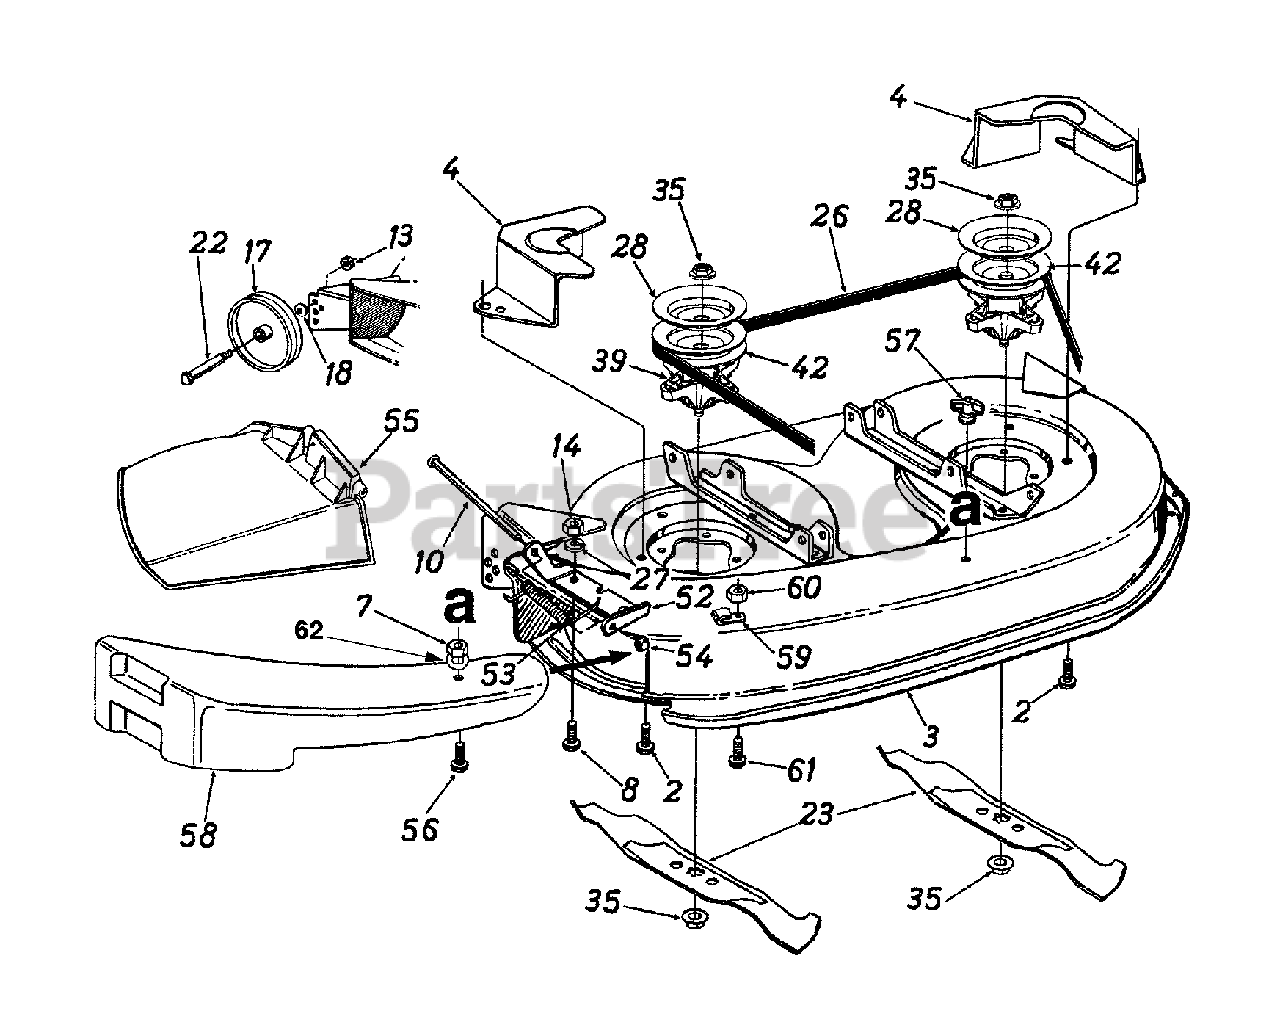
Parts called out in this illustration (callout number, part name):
2	Hex Wash. Hd. TT-Tap Scr. 5/16-18 x .75"
7	Hex L-Nut 1/4-20 Thd.
8	Hex Bolt 1/4-20 x .62"
10	Hinge Pin
13	Hex Top L-Nut 3/8-16 Thd.
14	Hex Nut 1/4-20 Thd. (Gr. 5)
17	Deck Wheel - 5"
18	Bell-Wash. .40" I.D. x .88" O.D.
22	Shld. Bolt .498" Dia. x 1.53"
23	3 in 1 Blade
26	V-Belt
27	Bell-Wash. 1/4" I.D.
28	Brake Disc
35	Hex Flange Nut 5/8-18 Thd.
39	Blade Spindle Ass'y.
42	5.75" Dia. Pulleys
52	Hinge Mtg. Brkt.
53	Torsion Spring
55	Chute Ass'y.
56	Hex Bolt 1/4-20 x 1" Lg.
57	Wing Nut 1/4-20 Thd.
58	Mulching Plug
59	Retainer Hook Brkt.
60	Hex Sems Nut 1/4-20 Thd.
61	Hex Bolt 1/4-20 x .62" Lg.
62	Flat Washer .28 ID x .74 OD
